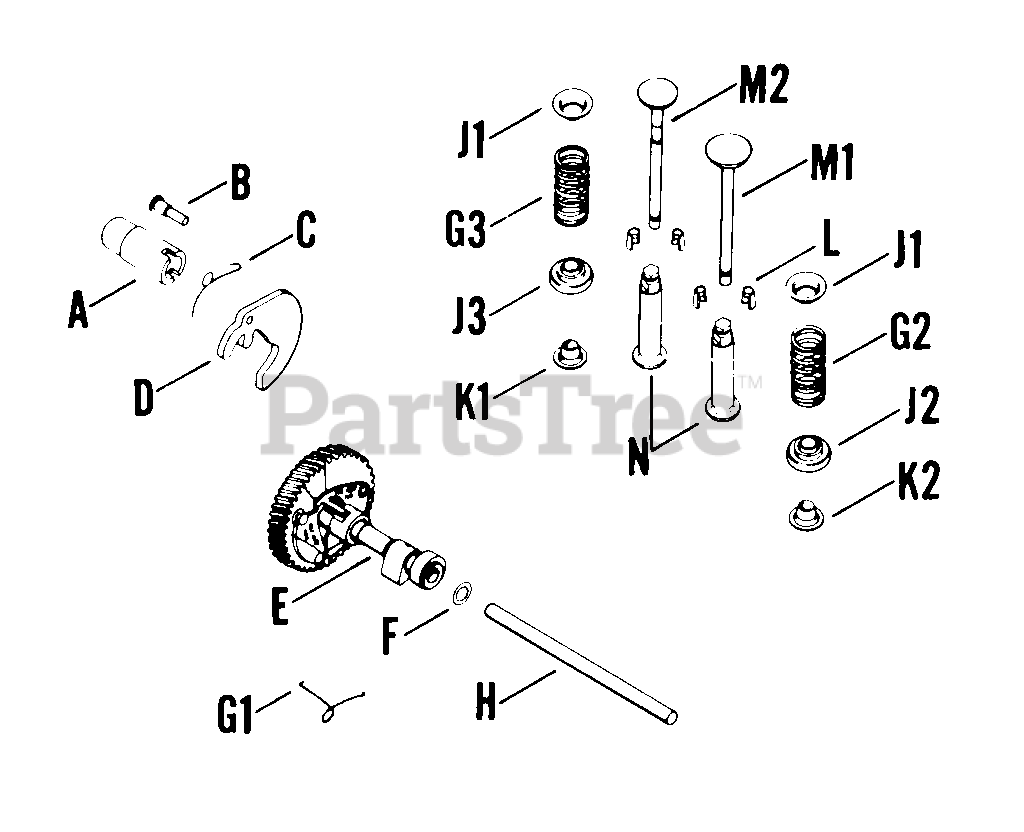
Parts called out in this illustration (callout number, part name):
C	SPRING - DISCONTINUED
E	CAMSHAFT - USE 47 010 06
F	SPACER (.005")
F	SPACER (.010")
G1	SPRING, ACTUATING-DISCONTINUED
G2	SPRING, EXHAUST VALVE
G3	SPRING, EXHAUST VALVE
H	PIN - USE 235193
J1	RETAINER, SPRING
K1	RETAINER, VALVE SPRING
K2	RETAINER, VALVE SPRING
L	KIT, RETAINER
M1	VALVE, INTAKE
